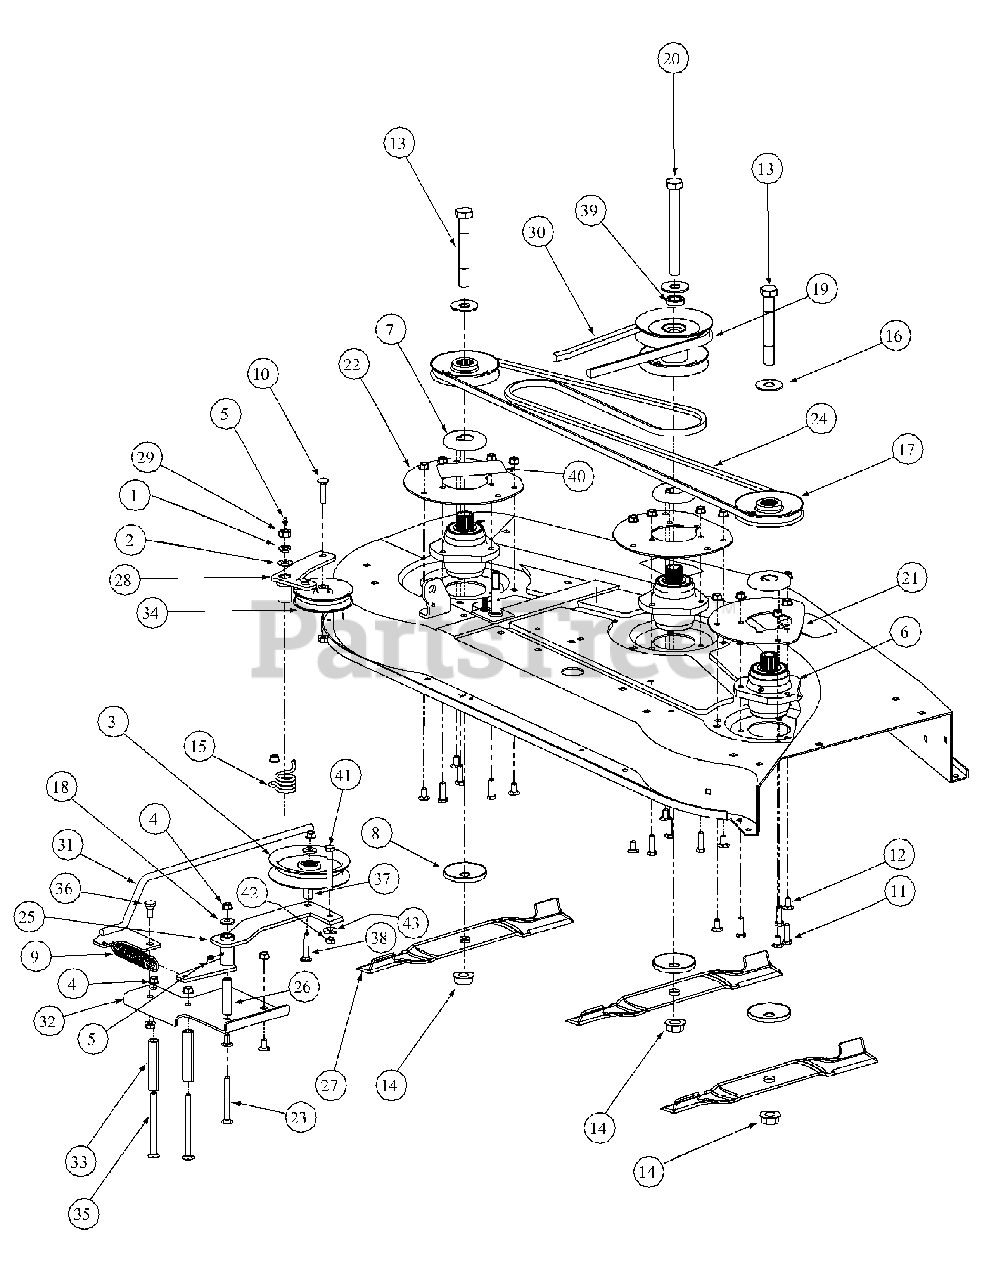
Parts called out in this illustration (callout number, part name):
1	Lock Washer, 1/2
2	Flat Washer, SAE, 1/2
3	Idler, Pulley
4	Hex Nut, 3/8-16, Flange Lock
5	Grease Fitting, 1/4-28 x 3/16
6	Spindle Assembly, Cast Iron
7	Cup, Spindle Top
8	Cup, Spindle Bottom
9	Extension Spring, 1.0 OD x 5.125
10	Carriage Bolt, 3/8-16, 1.25
11	HHCS, 3/8-16, 1.25
12	Carriage Bolt, 3/8 -16 x .75 Long
13	HHCS, 3/4-16, 6.00
14	Nut Hex Flange, 3/4-16
15	Spring Idler Torsion
16	Flat Washer, .781 ID, 2.0 OD, .105
17	Pulley-V 4.65 P.D.
18	Washer, Flat, .406 ID: 1.0 OD:.105
19	Double Pulley
20	HHCS: 3/4-16, 8.00
21	Cover Plate, Right Hand
22	Cover Plate
23	Carriage Bolt, 3/8-16 x 3.5 Long
24	V-Belt Deck, "A" Sec. x 122" Long
25	Arm Assembly, Bearing Top Idler
25	Bearings
26	Spacer,.39 ID x .625 OD x 2.7
28	Arm Assembly, Idler, Bearing Mower Deck
28	Bearings
29	Hex Nut, 1/2-20
30	V-Belt PTO, B Section, x 83.2 Lg.
31	Rod Assembly, Mount, Idler Spring
32	Bracket Mount, 54 Idler Arm
33	Spacer, .405 x .75 x 3.875
34	Idler Pulley, 4.06"
35	Carriage Bolt, 3/8-16, 5.00
36	Shoulder Screw, .50 x .27 Long, 3/8-16
37	Spacer, .385 ID x .75 OD x 1.063
38	Carriage Bolt, 3/8-16, 2.50
39	Spacer, Caster
40	Decal, Warning Shield Missing
41	Belt Retaining Stud, 3/8"
42	Nut, Jam, 3/8-16
43	Lock Washer, SAE, 3/8
